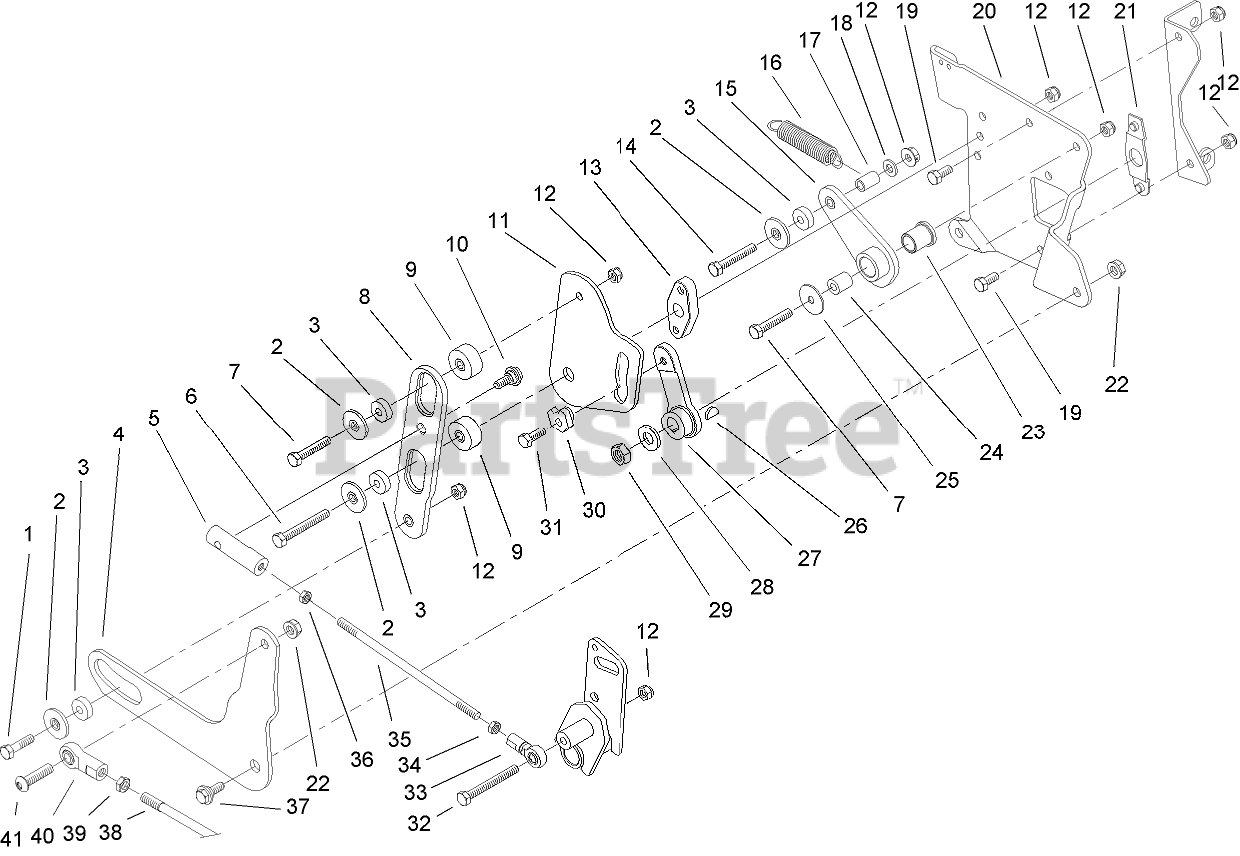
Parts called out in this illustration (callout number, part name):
1	SCREW-HH
2	RETAINER-BEARING
3	BEARING-BALL
4	SLIDER-LIFT
5	END-ROD, RH
6	SCREW-HH
7	SCREW-HH
8	SLIDER-CONTROL, SPEED
9	STANDOFF-CAM PLATE
10	BOLT-SHOULDER
11	PLATE-CAM
12	NUT-LOCK, NI
13	STANDOFF-SLIDER
14	SCREW-HH
15	ARM-RETURN TO NEUTRAL
16	SPRING-IDLER
17	STANDOFF-SPRING
18	WASHER-PLAIN
19	SCREW-HH
20	PLATE-CONTROL
21	LOCATOR-CONTROL PLATE
23	BUSHING-FLANGED
24	SPACER
25	WASHER-FLAT
26	KEY-WOODRUFF
27	ARM-CONTROL, SPEED
28	WASHER-FLAT
29	NUT-LOCK, NI
31	SCREW-THREAD LOCKING
32	SCREW-HH
33	END-ROD, RH
34	NUT-JAM
35	ROD-SLIDER TO PIVOT
36	NUT-JAM
37	BOLT-SHOULDER
38	ROD-LIFT
39	NUT-HJ
40	END-ROD, FEMALE
41	SCREW-HSBH
